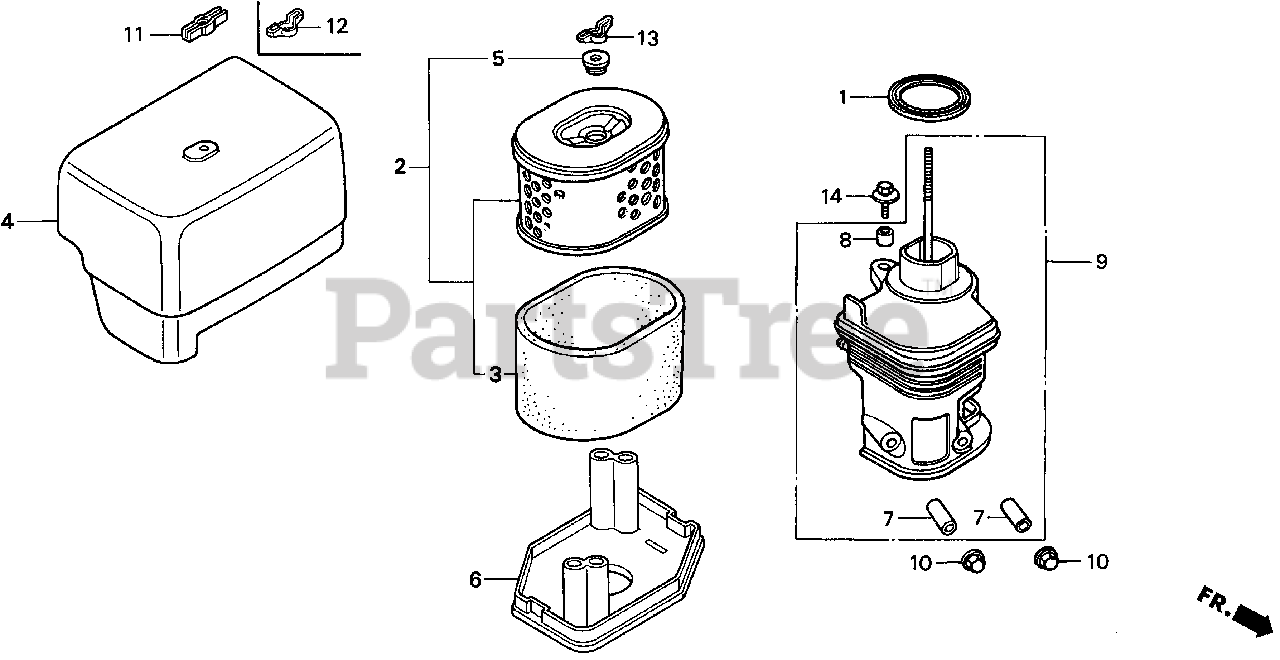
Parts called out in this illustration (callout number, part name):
1	GASKET, ELBOW
2	ELEMENT, AIR CLEANER
3	FILTER (OUTER)
4	COVER, AIR CLEANER
5	GROMMET, AIR CLEANER
6	NOSE, MUFFLER
7	COLLAR, AIR CLEANER
8	COLLAR B, AIR CLEANER
9	ELBOW, AIR CLEANER
10	NUT, CAP (6MM)
10	NUT, FLANGE (6MM)
11	WINGNUT, AIR CLEANER COVER
11	WINGNUT (6MM)
12	WINGNUT, TOOL BOX SETTING
13	WINGNUT, TOOL BOX SETTING
14	BOLT-WASHER (6X20)
